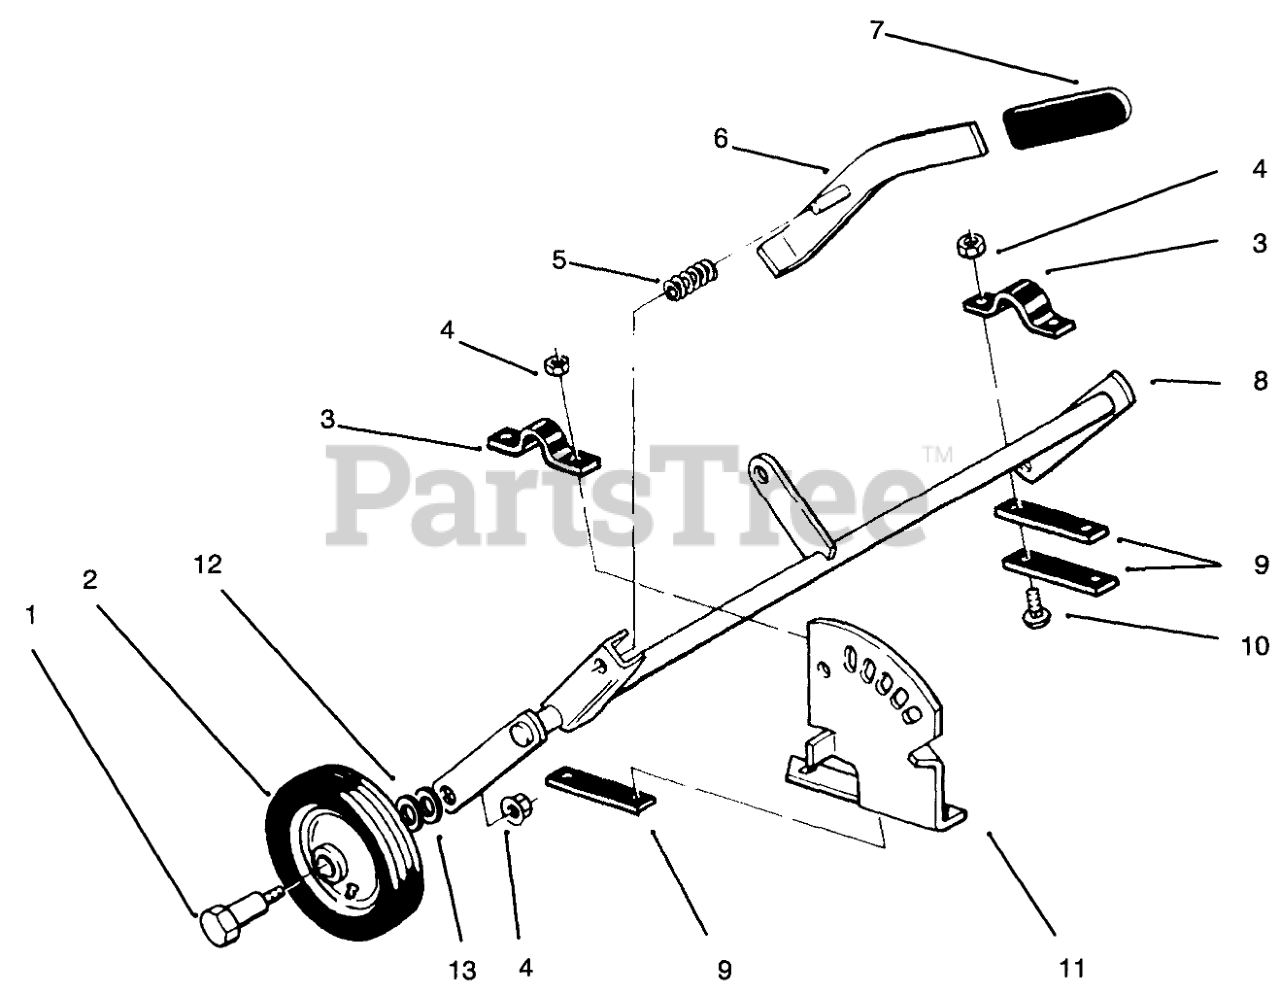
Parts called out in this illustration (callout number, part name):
1	BOLT-SHOULDER
2	WHEEL ASM
4	NUT-HEX
5	SPRING-COMPRESSION
6	Lever
8	Gage Wheel Support
9	Bar
10	BOLT-CARR
11	Quadrant
12	WASHER
13	WASHER
